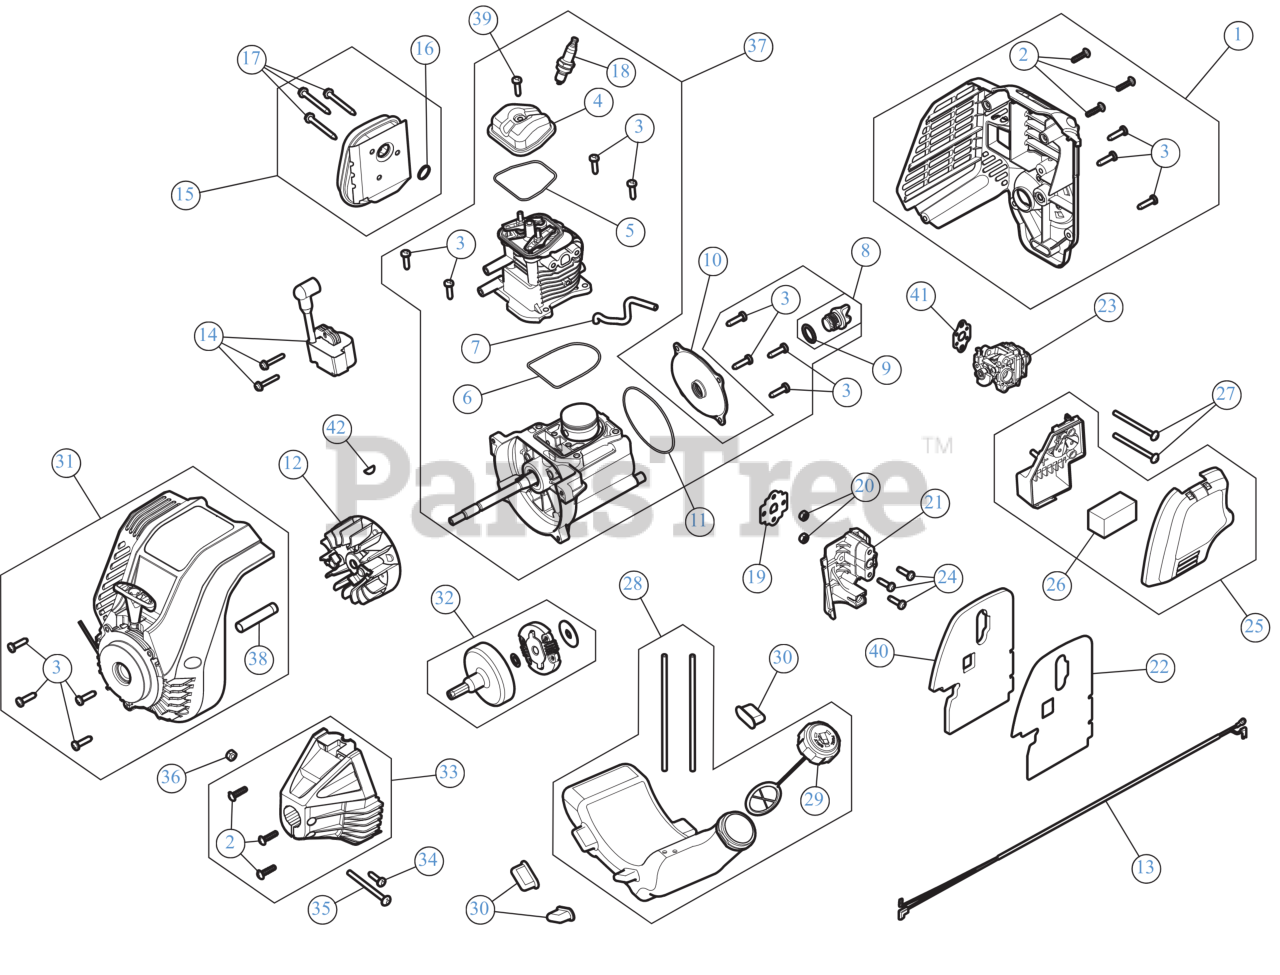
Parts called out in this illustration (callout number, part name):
1	REAR ENGINE COVER
2	SCREW 8-16 x 3/4
3	SCREW M5-0.8 x 19
4	ROCKER COVER
5	O-RING
6	O-RING CYL AC5
7	BREATHER HOSE
8	OIL PLUG
9	RING, OIL PLUG (AC
10	CRANKCASE COVER
11	O-RING CRNKCSE CVR
12	FLYWHEEL ASSEMBLY AC3.1
13	LEAD WIRES
14	MODULE ASSEMBLY
15	MUFFLER ASSEMBLY
16	GASKET/MUFFLER
17	SCREW M5 x 44MM
18	SPARK PLUG 4 CYCL
19	GASKET/INSULATOR
20	NUT 10-32
21	CARB INSULATOR
22	GASKET
23	CARBURETOR
24	SCREW, M5 X18
25	AIR CLEANER COVER
26	AIR FILTER
27	SCREW 10-32X2.5
28	FUEL TANK ASSEMBLY
29	FUEL CAP ASSEMBLY 43MM-6 W/O HOLE
30	FUEL TANK PADS
31	STARTER HOUSING
32	CLUTCH ASSEMBLY
33	CLUTCH COVER
34	SCREW, 8-32 x .312 P
35	SCREW
36	HEX NUT
37	SHORT BLOCK
38	SPACER :2.165"
39	SCR, VALVE COVER
40	HEAT SHIELD
41	CARBURETOR GASKET
42	WOODRUFF KEY #403-.125 x .375
